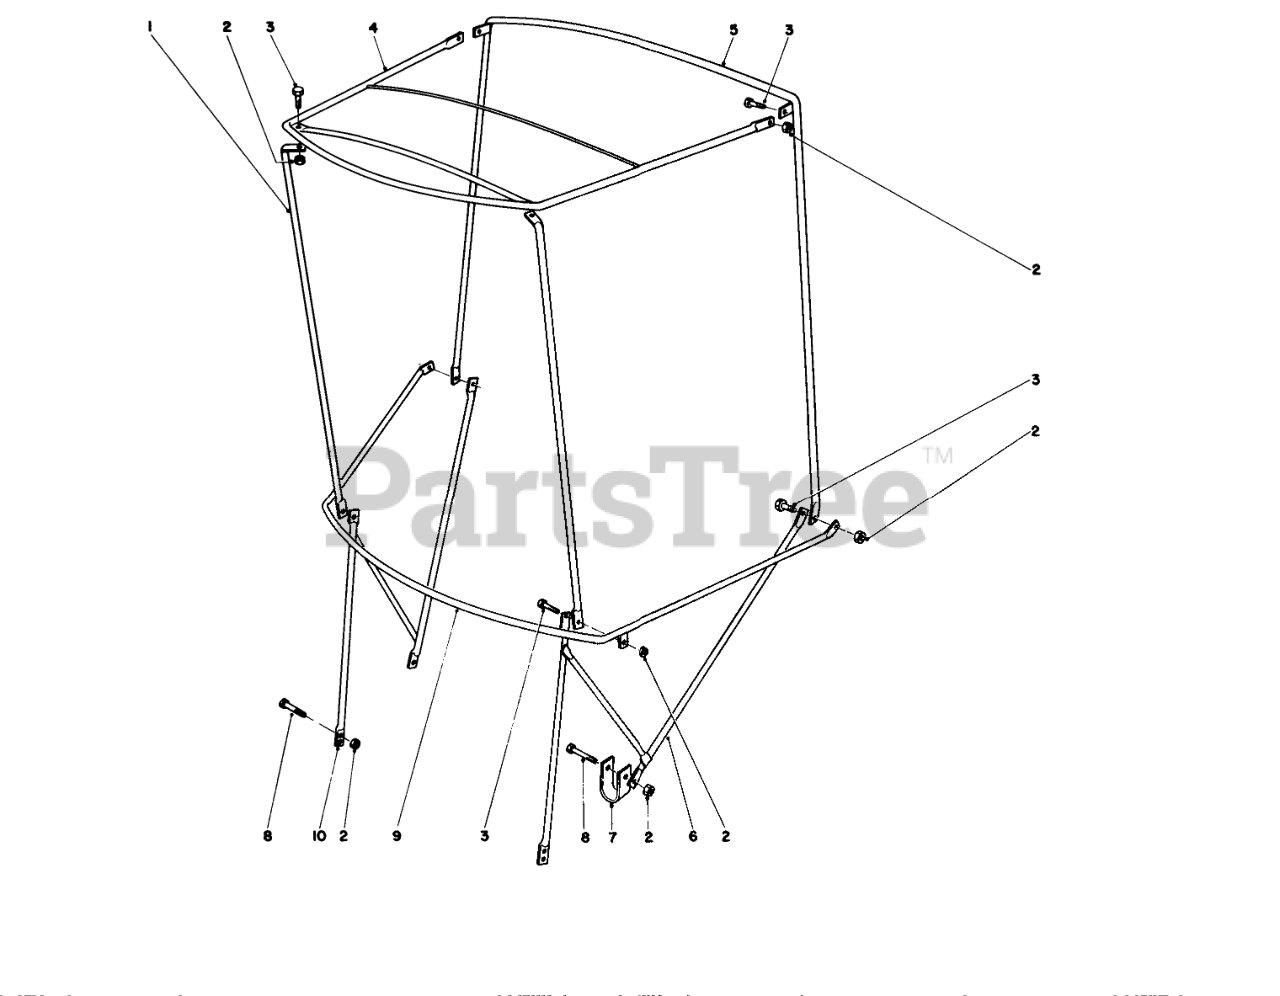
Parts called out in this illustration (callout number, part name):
2	NUT-HEX, SIDE DEFORM
3	SCREW-HH
4	FRAME-TOP
5	BOW-VERTICAL, REAR
6	ATTACHING BRKT L
7	U CLAMP
8	SCREW-HH
9	BOW-CURVED
10	ATTACHING BRKT R
